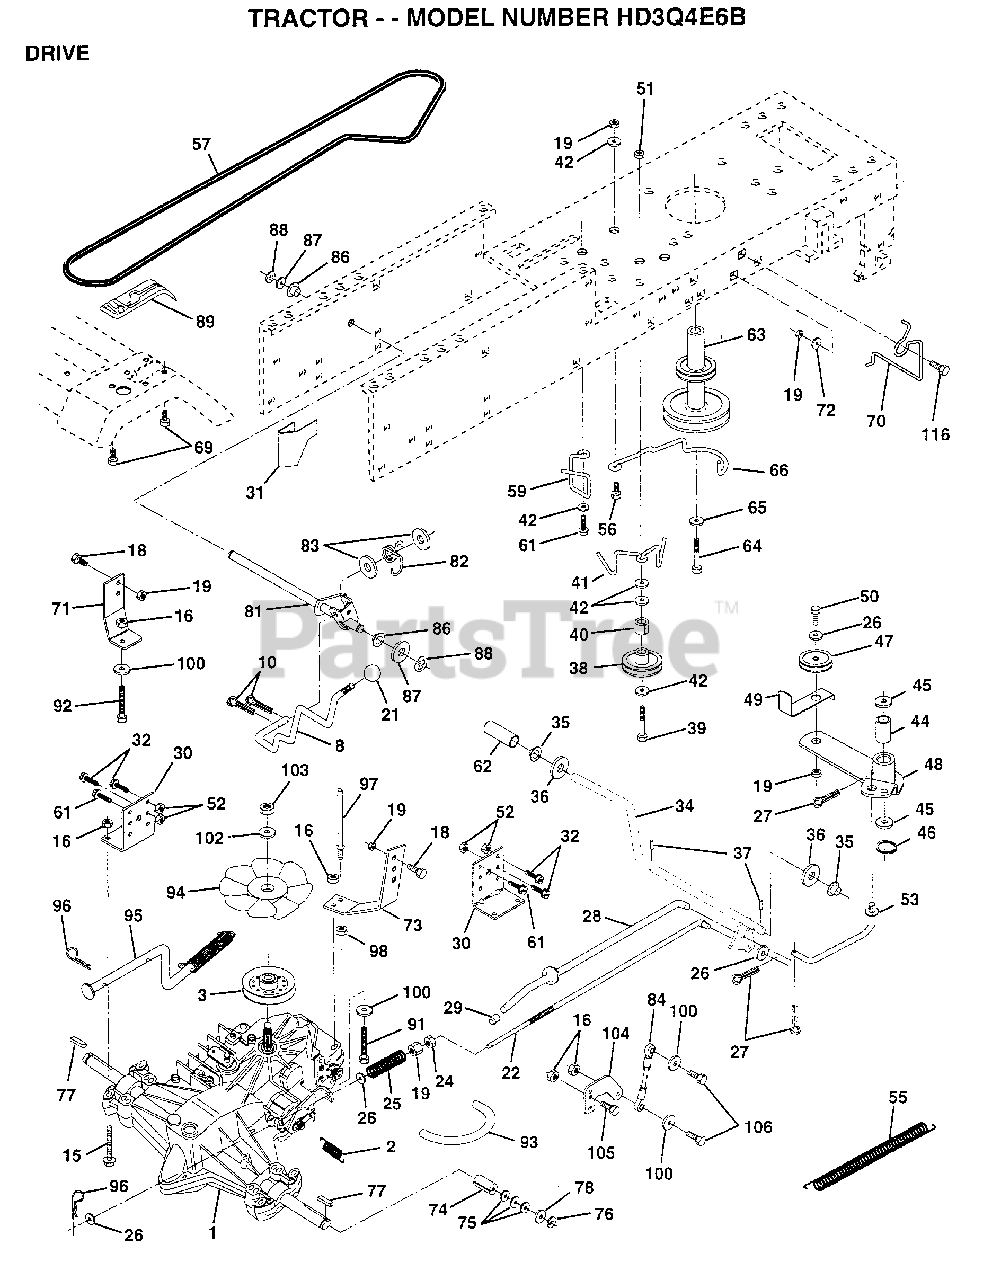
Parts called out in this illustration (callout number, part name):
1	TRANSAXLE.3100650
2	SPRING RET BRAKE
3	PULLEY.TRANSAXLE
8	ROD SHIFT FEND LT
10	PIN COTTER 1/8
15	BOLT.HX.FLG.5/16
16	NUT
18	BOLT
19	NUT
21	KNOB T (1/2-HOLE)
22	ROD.BRAKE.HYDRO.
24	NUT
25	SPRING ROD LT
26	WASHER
27	COTTER PIN
28	ROD.BRAKE.PARK.LT
29	PLUNGER CAP T
30	TRANSAXLE MTG BKT
31	"KEEPER,BELT LH T"
32	BOLT
34	SHAFT FOOT PEDAL
35	NYLON BEARING
36	WASHER LT
38	PULLEY.IDLER.FLAT
39	BOLT
40	SPACER T
41	KEEPER BELT
42	WASHER
44	"LY, BEARING"
45	WASHER LT
46	KLIP RING
48	ARM IDLER
49	RETAIN BELT
53	"LINK, CLUTCH T"
55	"SPRING, RETURN LT"
57	"BELT.GD DRV 82"""
58	KEEPER BELT LH
59	KEEPER BELT CNTSP
61	SCREW
62	PEDAL COVER T
63	PULLEY.ENGINE
64	BOLT
65	LOCKWASHER
69	SCREW HEXWSH H-L
70	KEEPER BELT ENG
71	STRAP TORQ LH HYD
72	WASHER
73	STRAP TORQ RH HYD
74	SPACER SPLIT
75	WASHER
76	E-RING LT
77	SQUARE KEY
78	WASHER
82	"SPRING,TORSION"
83	WASHER
84	ROD.TIE.BALL.4.75
86	BUSHING
87	WASHER D
88	KLIP RING
92	HEX BOLT
93	"LINE FUEL HYD 4"""
94	"FAN 7"" HYDRO"
96	RETAINER M
97	BOLT KEEPER RH
98	NUT
100	WASHER M
102	WASHER BELLEVILLE
104	ARM CONTROL HYDRO
105	SCREW CAP 5/16-18
106	BOLT
116	BOLT RDHD 3/8-16
